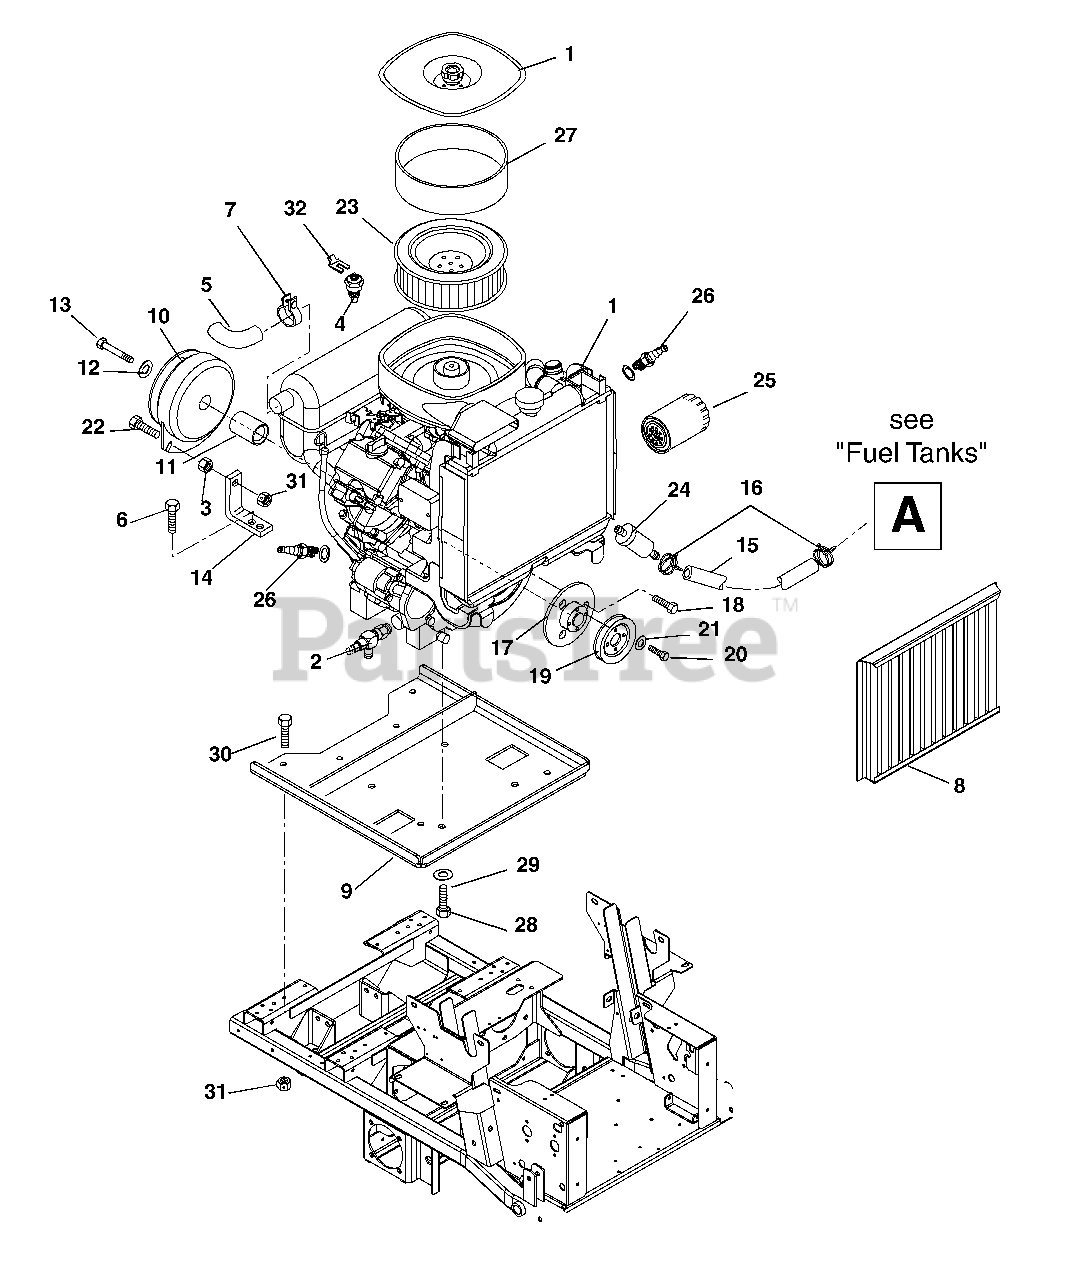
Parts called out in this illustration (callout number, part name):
1	Engine, 27HP Gas Kawasaki
2	Drain, Oil
3	Nut-Hex .31-18
4	Temperature Sender
6	Screw-Tapping .38-16 x .75 Hex Washer Head
7	Clamp, Muffler Assembly
8	Screen (Gas)
9	Weldment, Engine Plate (Gas)
10	Clutch, Electric
11	Spacer, Clutch
12	Washer-Locking .44 x .109
13	Bolt-Hex M10 x 1.5 x 60 8.8
14	Anchor-Clutch
15	Gas Line-Bulk .25 ID
16	Clamp-Hose Wire .490/.510X.116
17	Adapter, Sheave (Kawasaki)
18	Bolt, M8-1.25 x 25
19	Sheave 3.50
20	Bolt-Hex .25-20 x .50 Grade 5
21	Washer-Locking .25 x .062 Regular
22	Bolt-Hex .31-18 x 1.50 Grade 5
23	Air Filter
24	Fuel Filter
25	Oil Filter
26	Spark Plug
27	Element, Precleaner
28	Bolt-Hex M10 x 1.5 x 20 Grade 5
29	Washer-Locking .44 x .109 Regular
30	Bolt-Hex .31-18 x 1.00 Grade 5
31	Nut-Locking-Nylon .312-18
32	Male Disconnect Adapter
